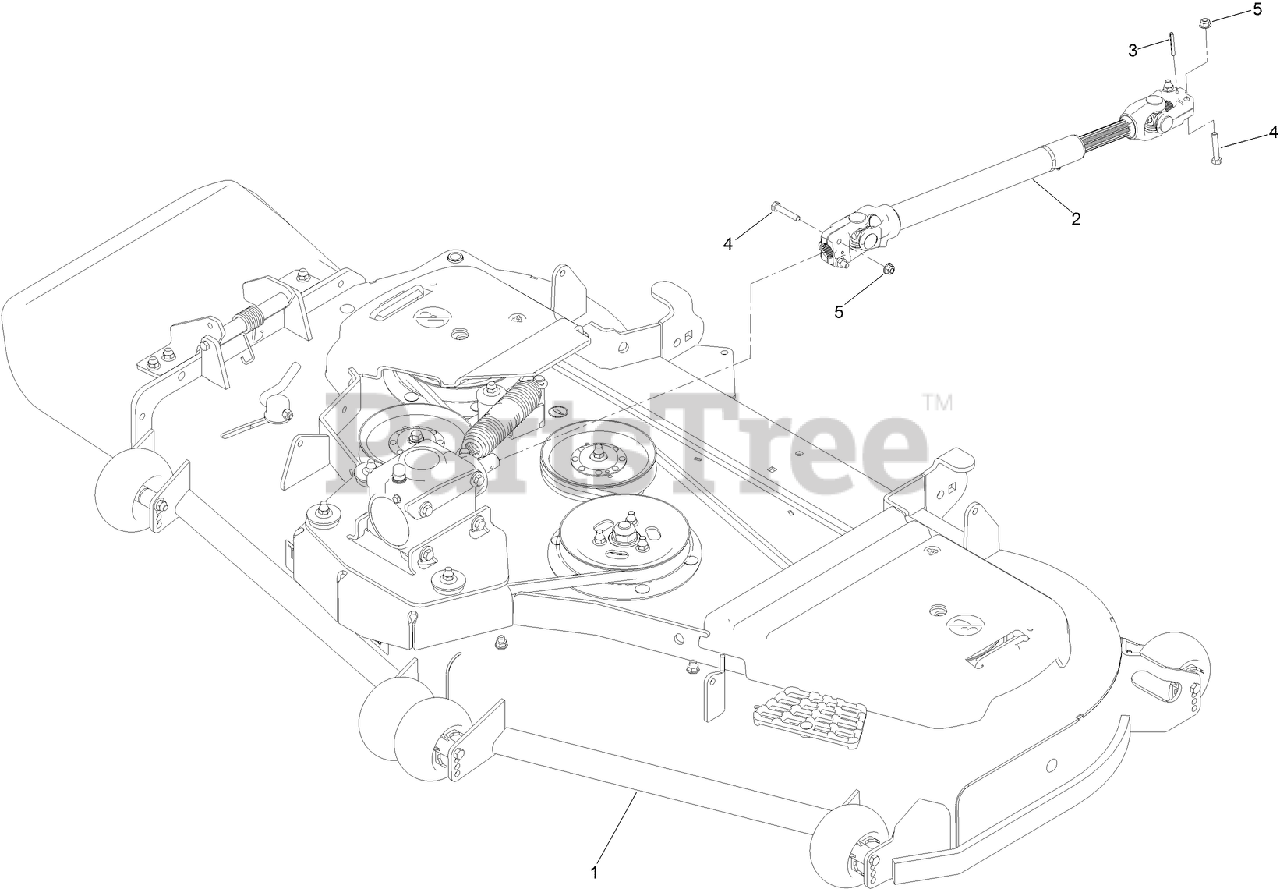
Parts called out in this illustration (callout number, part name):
1	DECK ASM
2	DRIVESHAFT ASM
3	PIN-ROLL
4	SCREW-HH
5	NUT-HF, NI
